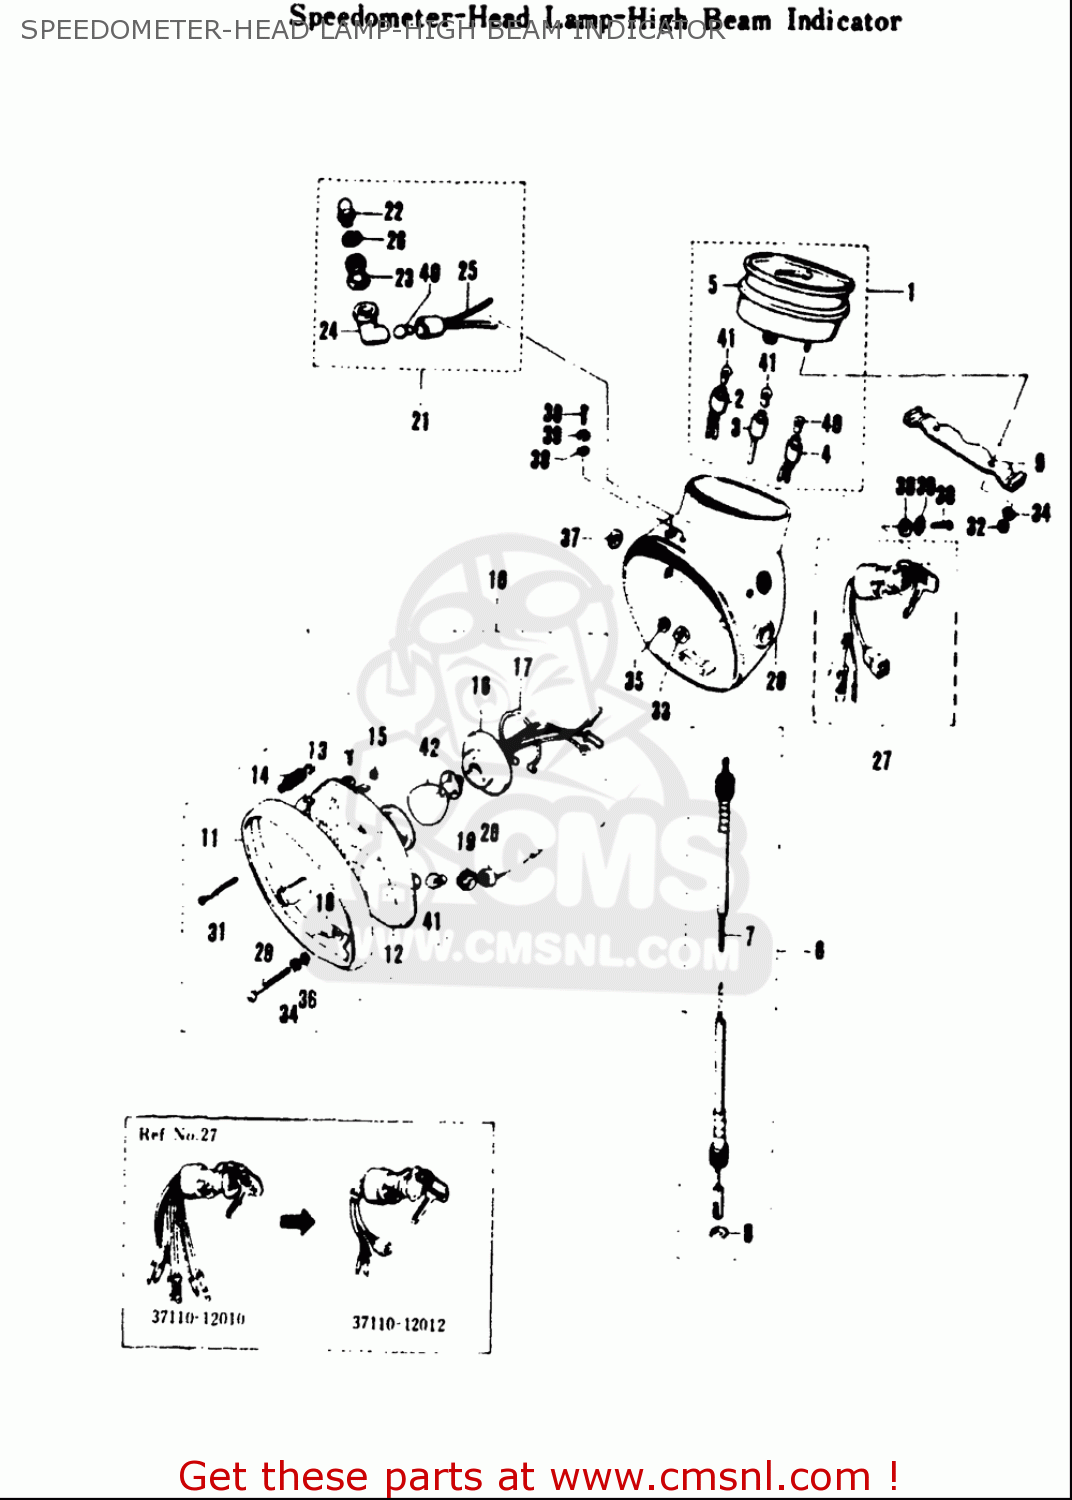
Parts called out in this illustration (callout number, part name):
8	SEAL,OIL METER CABLE
13	SCREW,LENS
29	SCREW
30	SCREW
32	NUT
33	NUT
34	WASHER,LOCK
35	WASHER,LOCK
36	WASHER
38	WASHER(4X12.5X0.3)
39	WASHER
40	BULB(6V1.7W,STANLEY,A61A)
41	BULB(6V/3W)
